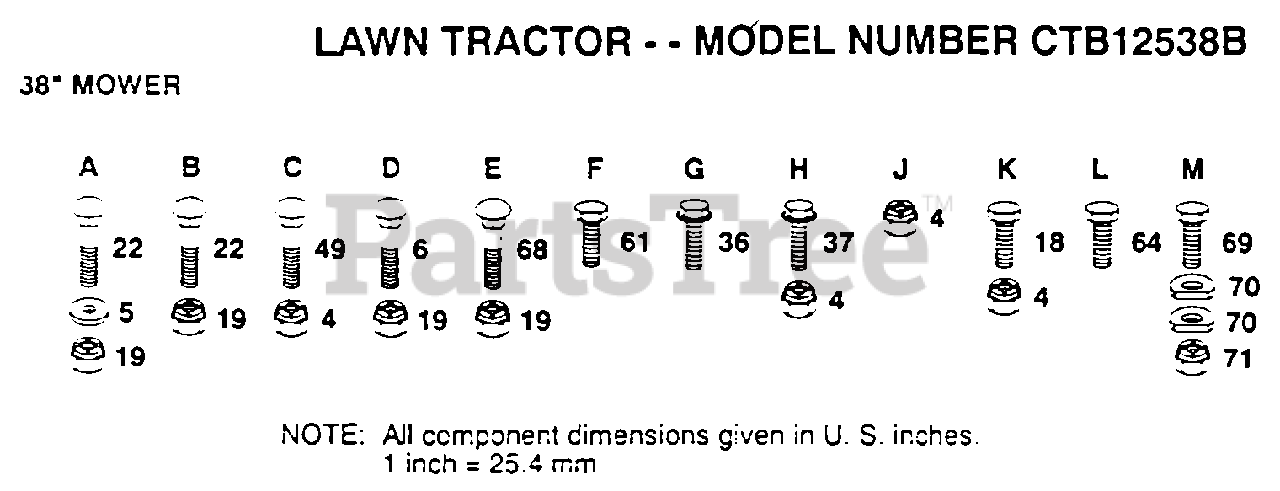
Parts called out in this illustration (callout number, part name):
5	WASHER M
6	BOLT
22	BOLT
36	SCREW
37	SCREW
49	BOLT
61	BOLT
64	BOLT.3/8-14X1.25
69	BOLT LT
70	WASHER T
